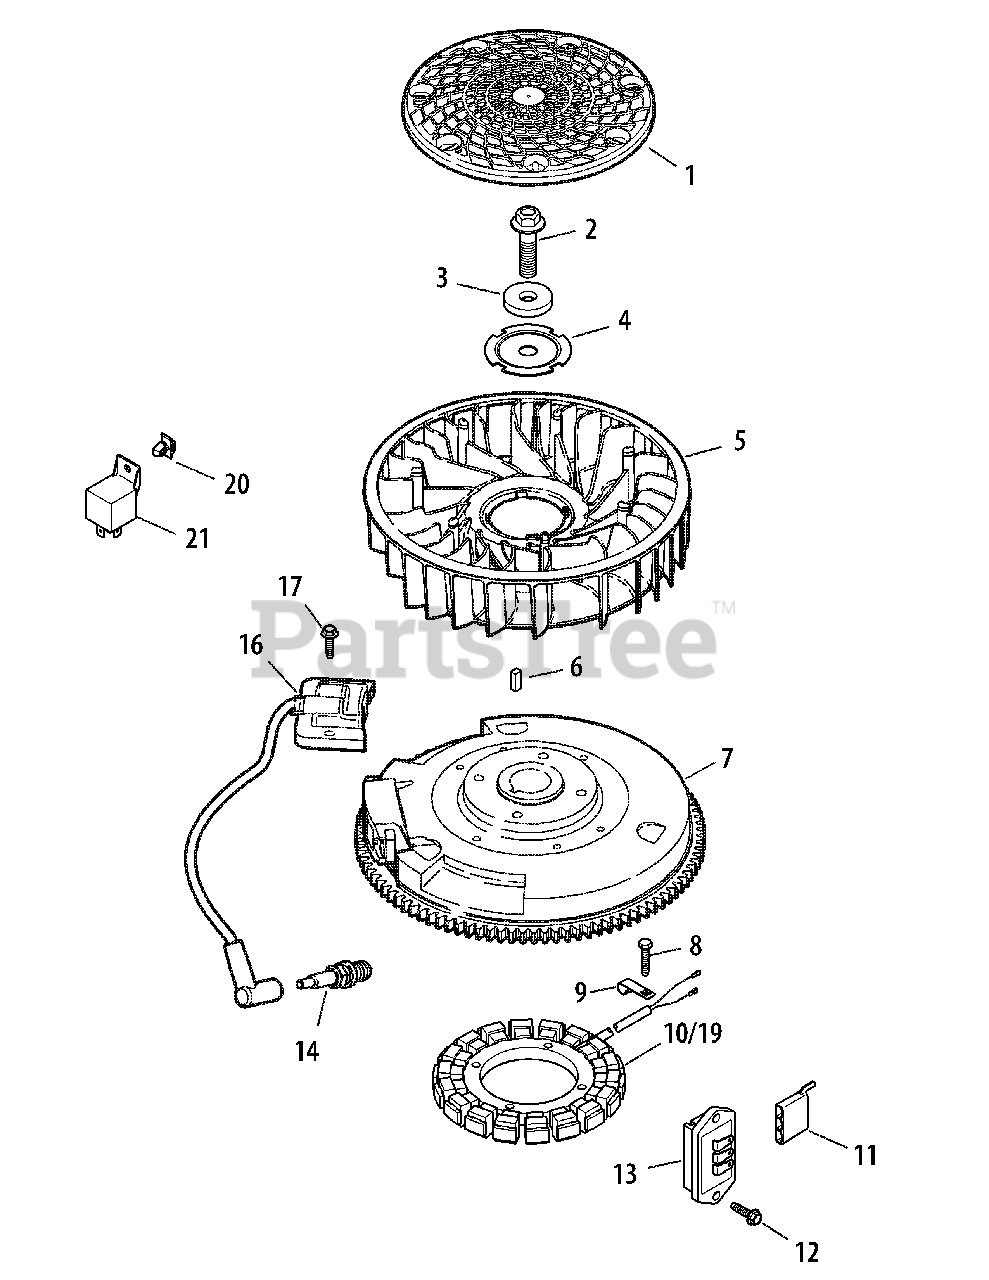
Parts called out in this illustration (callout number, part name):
2	Hex Flange Screw
4	Fan Mounting Plate
6	Straight Flywheel Key
7	Flywheel
8	Thd. Frm. Screw, M5 X 0.8 X 25
10	15 Amp Stator Kit - SV590
12	Flange. Screw, M5 X .8 X 20
13	Regulator/Rectifier
14	Spark Plug (Std)
16	Ignition Module (CDI Fixed)
17	Flange. Thd. Frm., M5 X .8 X 20
19	Stator Assembly Kit - SV600 (Incl. KH-25-454-07-S)
20	Push Wing Mount - SV600
21	Relay - SV600
